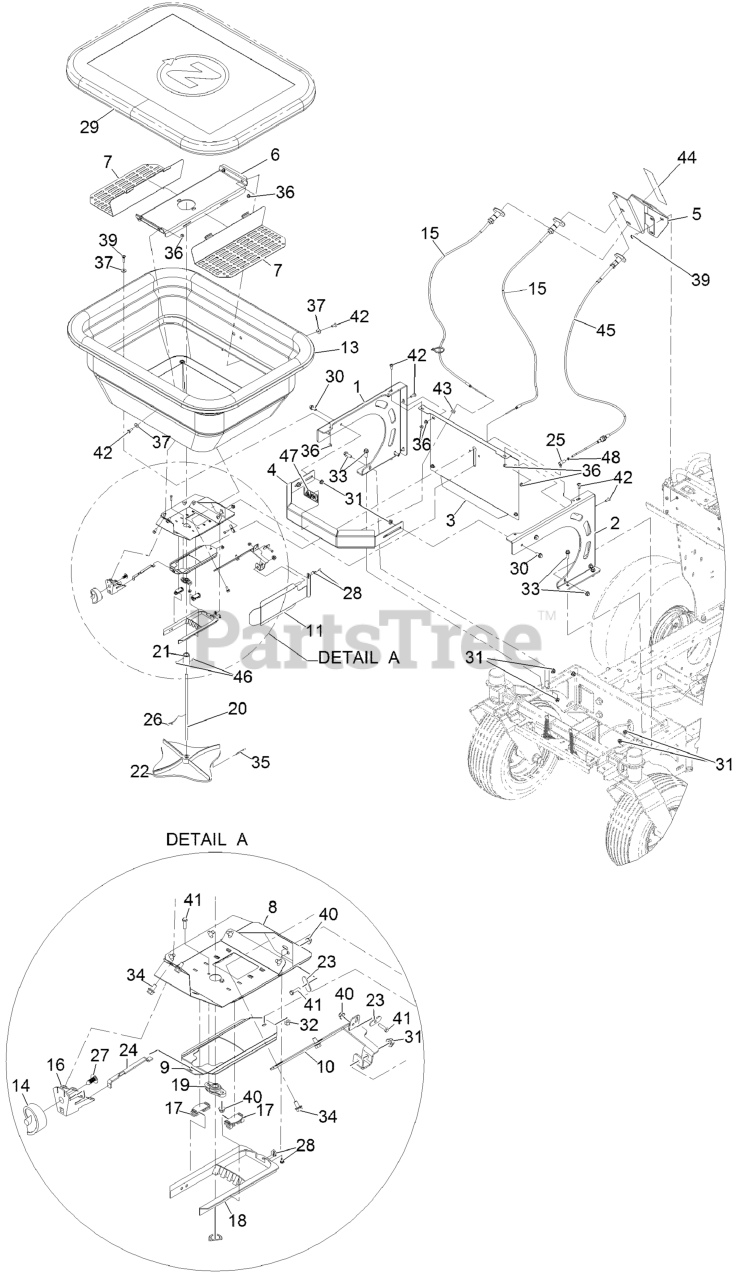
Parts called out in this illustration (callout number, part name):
1	Side-Hopper, Rt
2	Side-Hopper, Lt
3	Backshield-Hopper
4	BUMPER-FRONT, HOPPER
5	MOUNT-SPEEDOMETER
6	PAN-HOPPER, 220
7	SCREEN-HOPPER, 220
8	PLATE-BASE, HOPPER
9	Slide-Door, Hopper
10	Mount-Deflector, Side
11	Deflector-Side, Spreader
13	HOPPER-220LB
14	DIAL
15	CABLE-PUSH/PULL
16	MOUNT-DIAL
17	GUIDE-RATE, GATE
18	DIFFUSER
19	BEARING-FLANGE
20	SHAFT-HOPPER, 220
21	COUPLER-SS
22	SPINNER-SPREADER
23	RETAINER, CABLE
24	LINKAGE-GATE, RATE
25	BALL JOINT-SS
26	WIRE-AGITATOR
27	CLIP
28	RETAINER-CABLE, WIRE
29	COVER-HOPPER, LARGE
30	SCREW-HHF
31	Nut-Hex Flange
32	Nut,NYL Lock,#10-32,ST/ST 18-8
33	SCREW-HHF
34	SCREW-HHF
35	PIN-COTTER
36	Nut-Hex Flange
39	Screw-Hsbhf
40	Nut-Hex Flange
41	SCREW-HH
42	Screw-Hsbhf
43	Grommet-Rubber
44	Decal-Hopper Control
45	CABLE-PUSH/PULL
46	Screw-SQH
47	Decal-Dismemberment Hazard
48	Nut,Hex Jam Mch Scr,10-32,Sst
